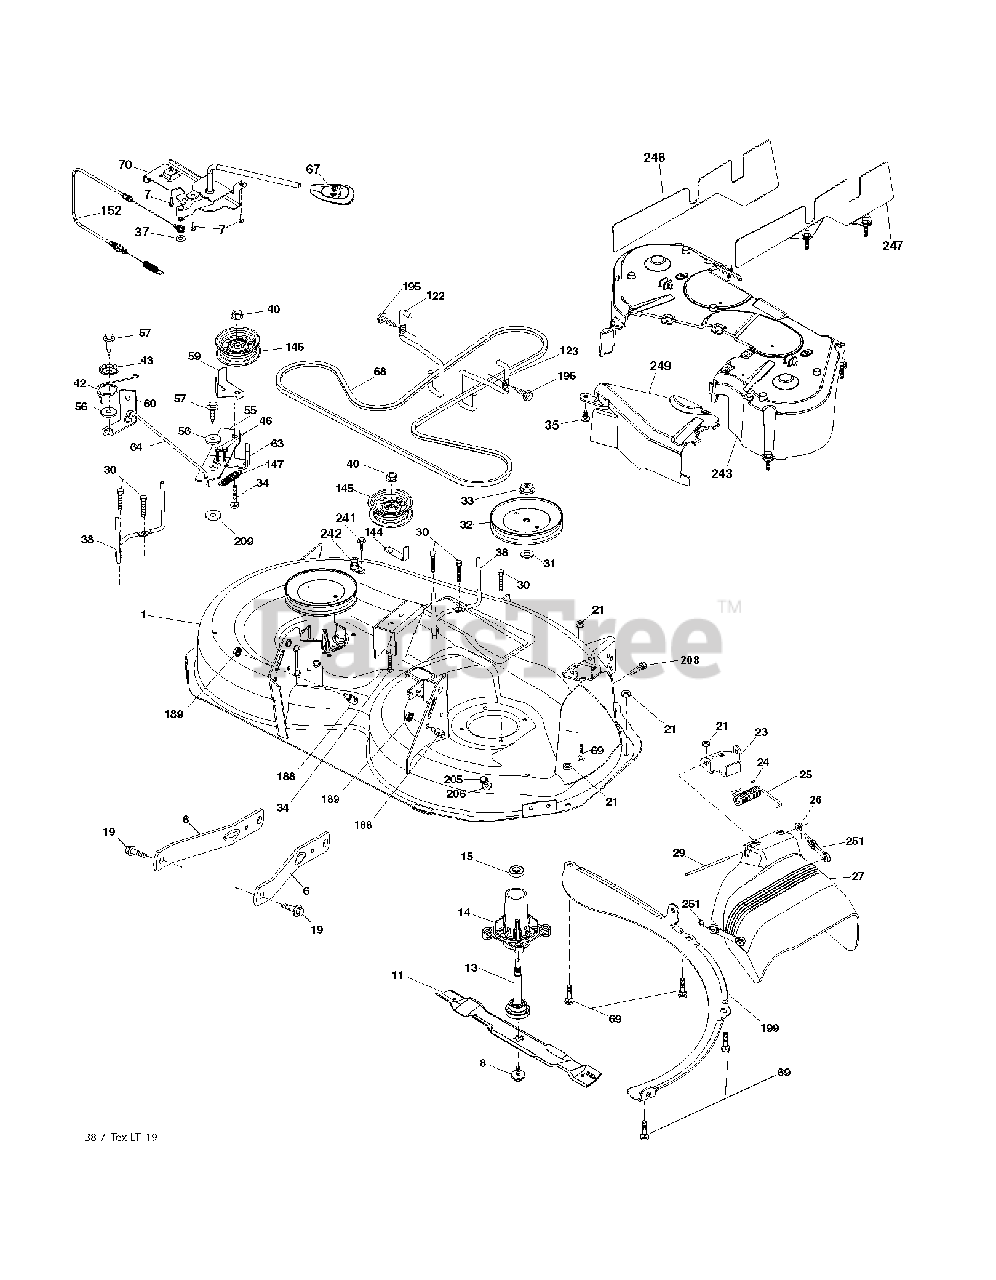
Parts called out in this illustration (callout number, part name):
6	ARM.SUSPENSION.MOWER.R
7	SCREW.#10 X 0.750.BOS THREAD
8	BOLT.WASHER.ASM.7/16-2
11	BLADE 38" PREMIUM
13	SHAFT.ASM.MDRL.N/GREASE.38
14	HOUSING MANDREL
19	BOLT.SHOULDER
21	LOCKNUT
23	BRKT.DEFLECTOR.38"2005+
24	CAP-SLEEVE LT
25	SPRING.TORSION.DEFLECT
26	NUT PUSH M
29	ROD.HINGE
30	SCREW, WASHER HEAD
31	WASHER.SPACER.MANDREL
32	PULLEY.MANDREL.5.0.PD.38"
33	NUT.FLANGE.LOCK.TOP
34	BOLT.3/8-16X1.50
35	FASTENER.XMAS.TREE
38	KEEPER BELT LH MANDREL
40	NUT LOCK FLG 3/8-16 UNC
42	SPRING.TORSION.BRAKE
43	SRPING.TORSION.RETAINE
46	SCREW.1/4-20X5/8
55	IDLER.ARM
56	SPACER.RETAINER
57	SCREW 3/8-16X1
59	GUARD, BELT
60	ARM BRAKE MOWER RH 38"
63	ARM BRAKE MOWER RH
64	LINK BRAKE
67	HANDLE.CLUTCH.CABLE.LT
69	BOLT
70	CLUTCH.ASM.MANUAL.LT.PRED
122	KEEPER BELT ENGINE LH
123	KEEPER BELT RH
144	KEEPER BELT
145	PULLEY.IDLER.48"PRIMARY
147	SPRING RETURN
152	CABLE.CLUTCH.MANUAL.
188	STUD.FASTNER.W/ANTI-ROTATE
189	NUT LOCK HEX FLANGE 5/16-18
195	SCREW, 3/8-16X3/4
199	BAFFLE VORTEX
205	SCREW
206	WASHER
208	SCREW 3/8-16X1/2
209	WASHER 12/32X2X10GA
242	PORT.WASHOUT
